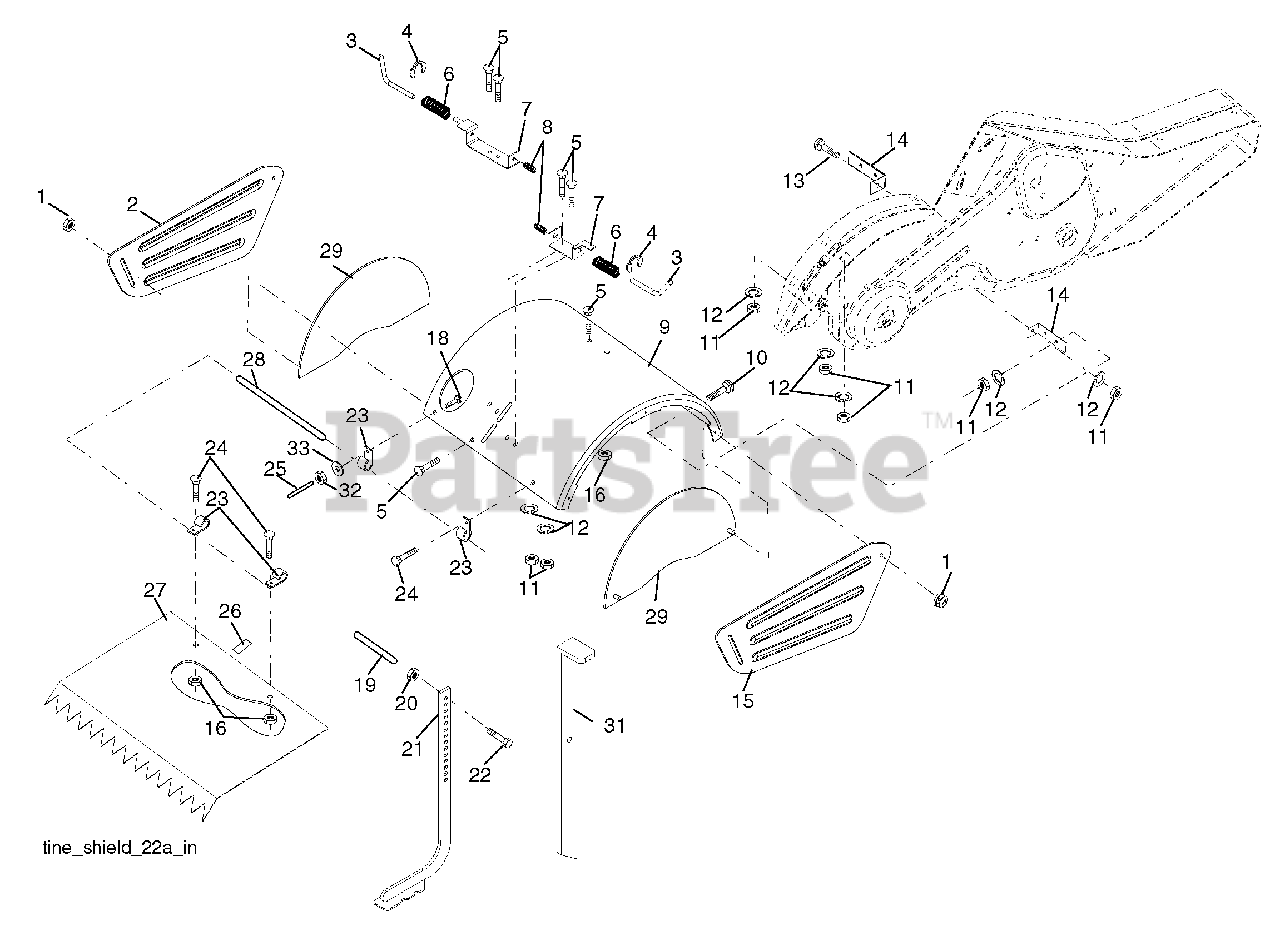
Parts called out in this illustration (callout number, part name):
1	Nut, Lock Hex Flange 5/16-18 unc
2	Shield, Side, Outer L. H.
3	Pin, Stake, Depth
4	Ring, Klip
5	Bolt Rdhd Sqnk 5/16-18 x 3/4
6	Spring
7	Bracket, Latch
8	Spring, Depth Stake
9	Shield, Tine
10	Bolt 5/16-18 x 1
11	Washer, Lock 5/16
12	Nut, Hex 5/16-18
13	Bolt, Carriage 5/16-18 x 1-1/4
14	Bracket, Shield Tine
15	Shield, Side, Outer R.H.
16	Nut, Hex Flange 1/4-20
18	Bolt, Carriage 1/4-20 x 1-1/4 Gr. 5
19	Grip
20	Nut, Hex 3/8-16
21	Stake, Depth
22	Bolt, Hex 3/8-16 x 2
23	Hinge
24	Bolt, Carriage 1/4-20 x 1/2
25	Cap, Vinyl
26	Pad, Idler
27	Shield, Leveling
28	Pin, Hinge
29	Shield, Side
31	Stake, Drag
32	Nut, Fin, Hex 1/4-20 unc
33	Washer Lock Hvy Helical 1/4
